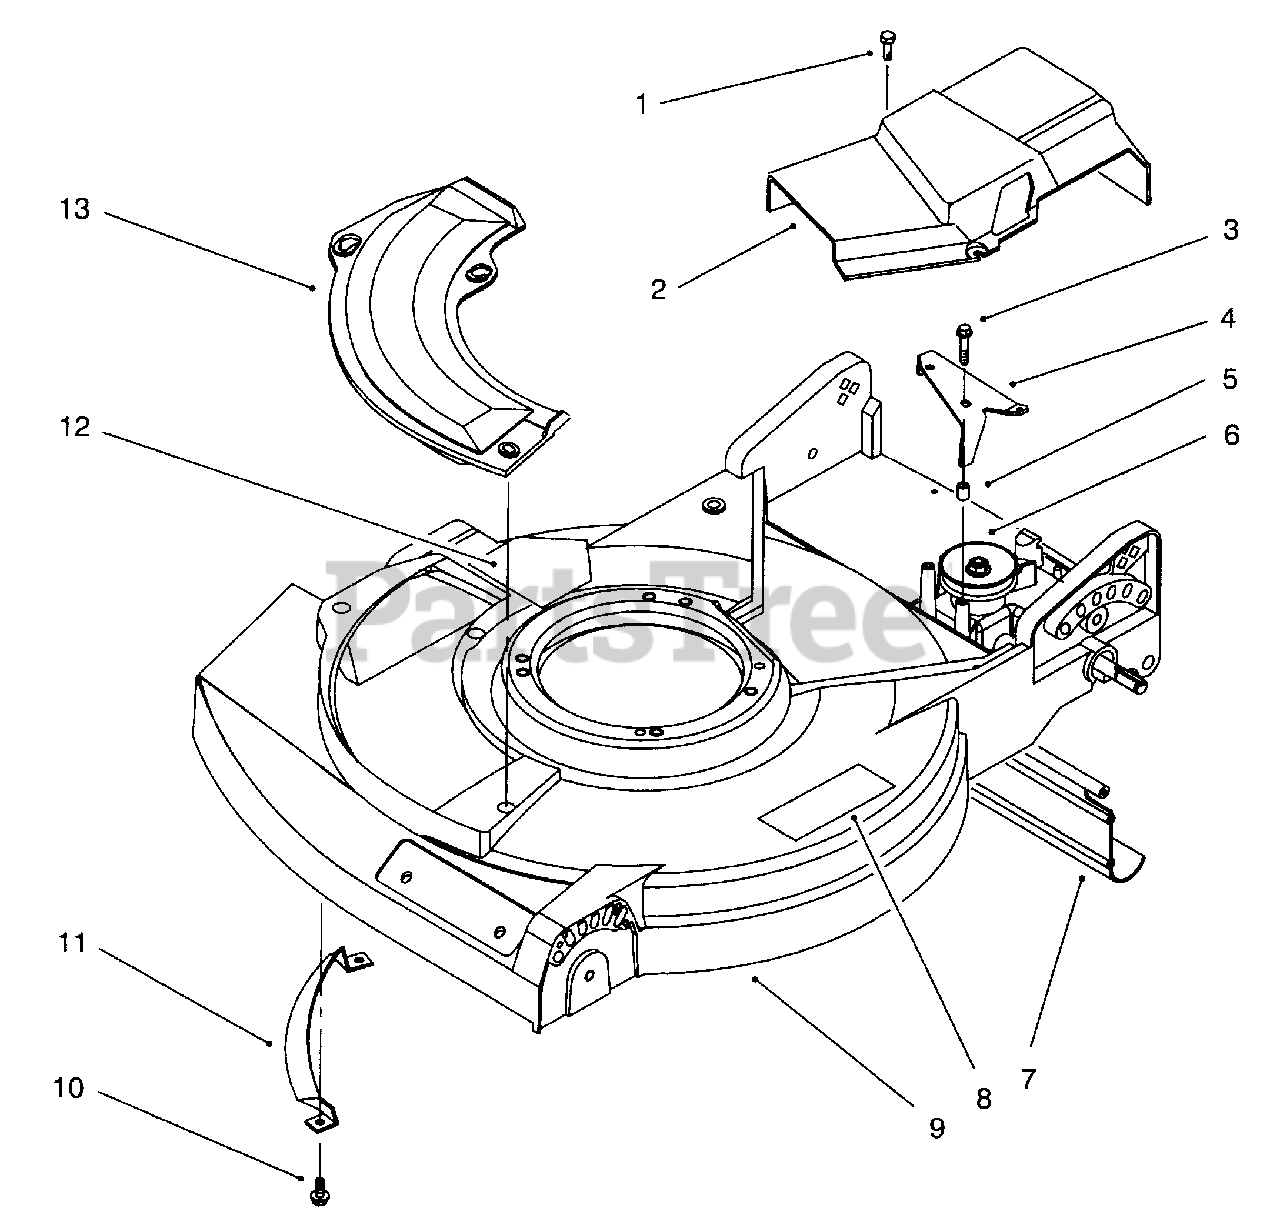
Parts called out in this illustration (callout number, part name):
1	Screw-Hex Washer Hd. Thread Forming
2	Cover-Transmission
3	Screw
4	Bracket-Actuator
5	Bushing-Spacer
6	Gear Case Assembly
7	Shield-Trailing
8	Decal-Warning
9	Housing-21" (Incl. Ref. #8, 12, & 14)
10	Screw-Hex Washer Hd.
11	Bar-Toe
12	Decal-Danger
13	Plate-Cover
